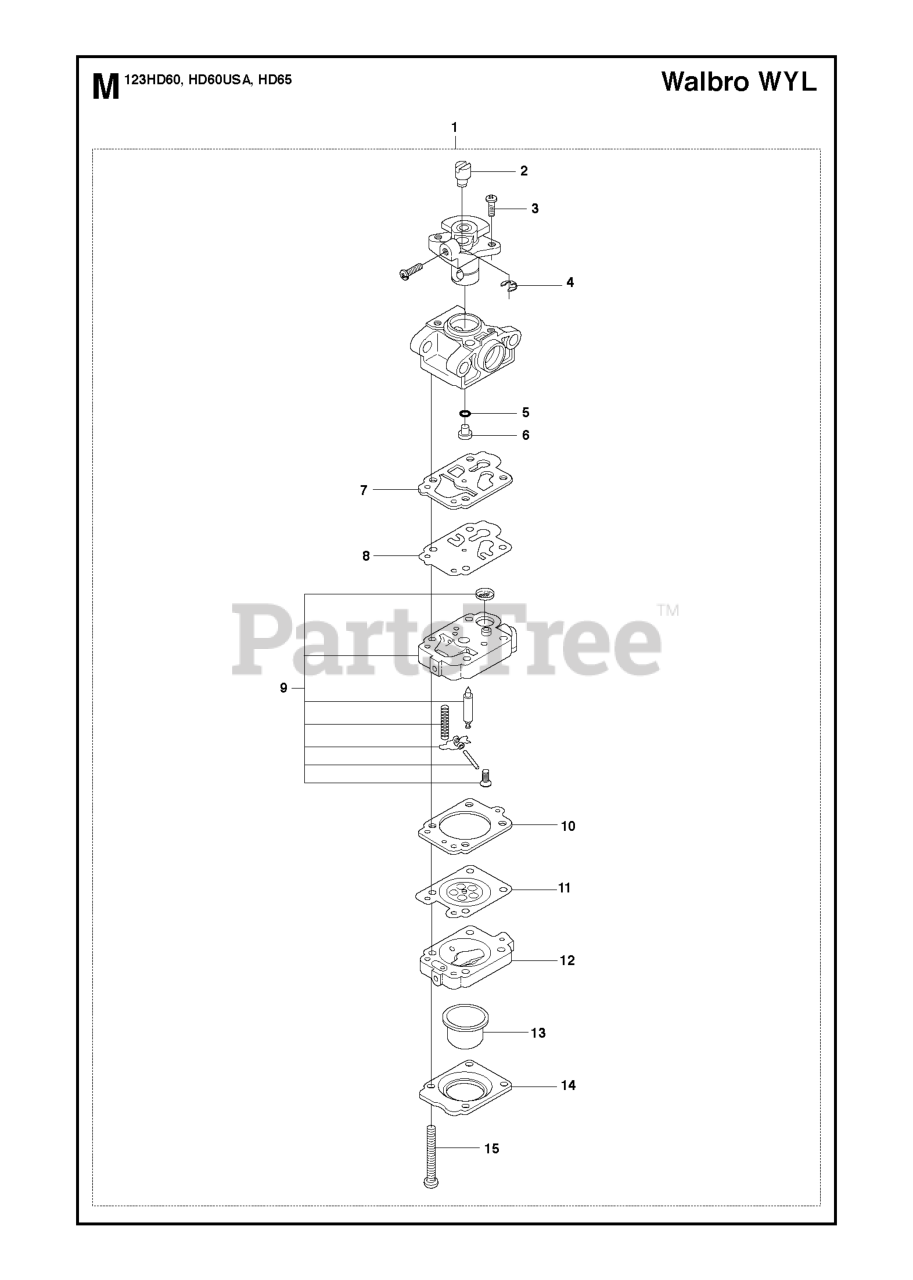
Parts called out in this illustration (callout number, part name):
1	CARBURETOR
2	CONNECTION
3	SCREW
4	RETAINING RING
7	GASKET
8	%GASKET
14	PUMP COVER
